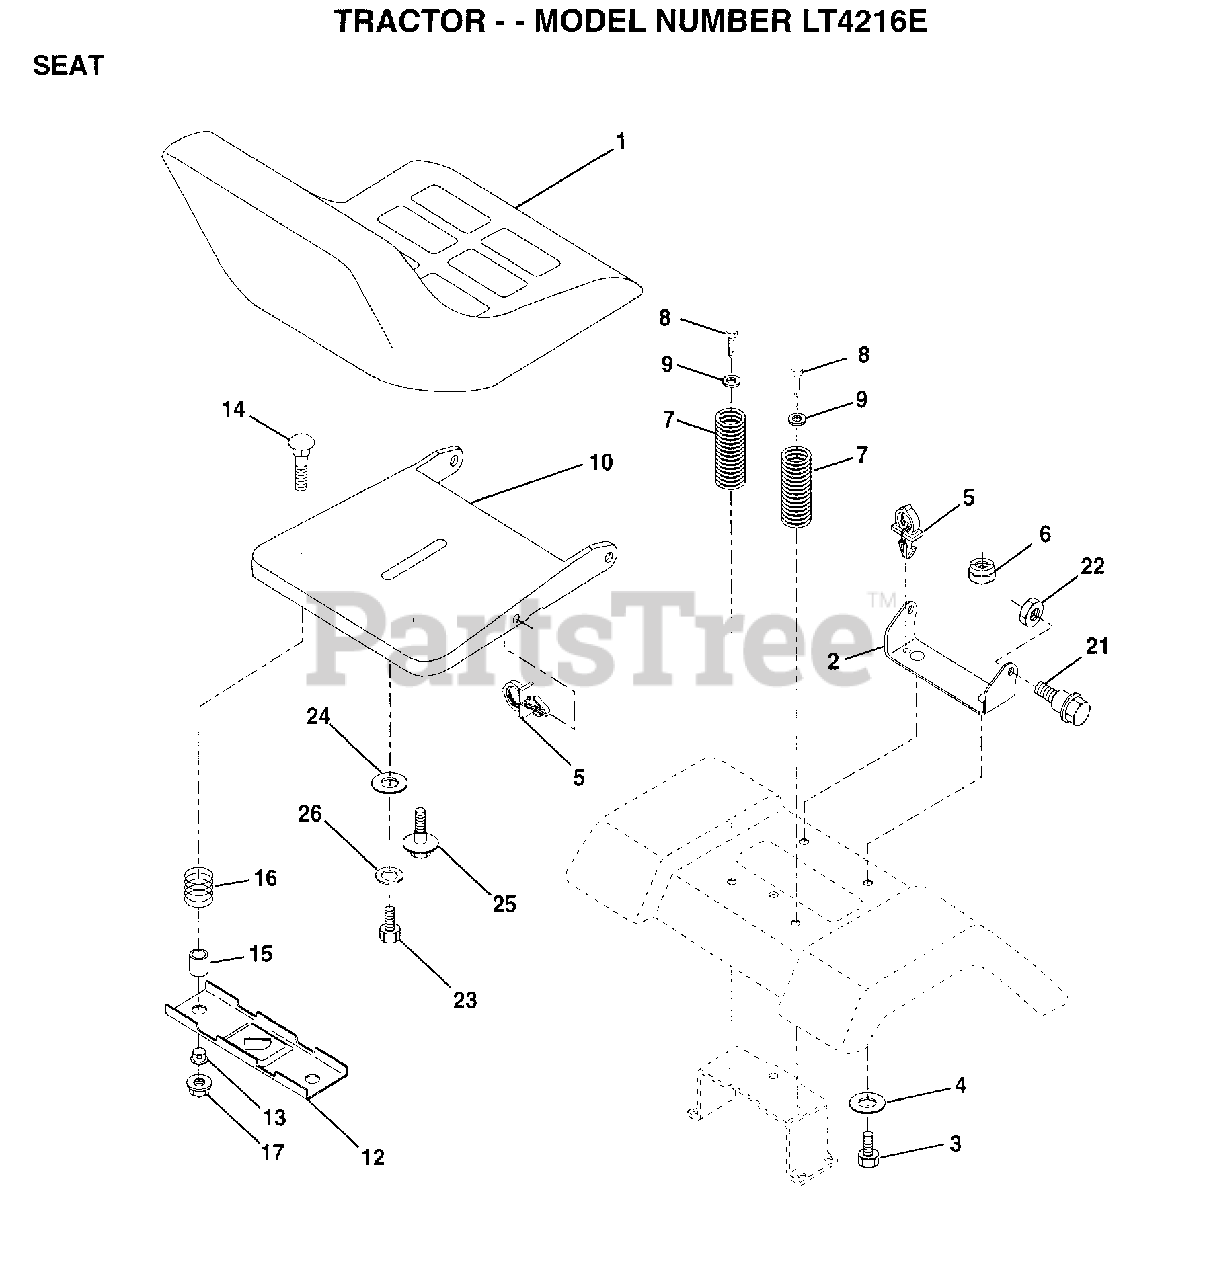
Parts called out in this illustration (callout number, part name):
1	SEAT
2	BRACKET PVT SEAT
3	BOLT
4	WASHER PM
5	CLIP.PUSH-IN.HING
6	NUT
7	SPRING COMPRESSIO
8	SCREW GTV
9	WASHER
12	BRKT SWITCH
13	BUSHING
15	SPLIT SPACER
16	SPRING
21	BOLT.SHLD.5/16-18
22	NUT
23	BOLT
24	WASHER
25	"BOLT,SHOULDER"
26	LOCKWASHER
